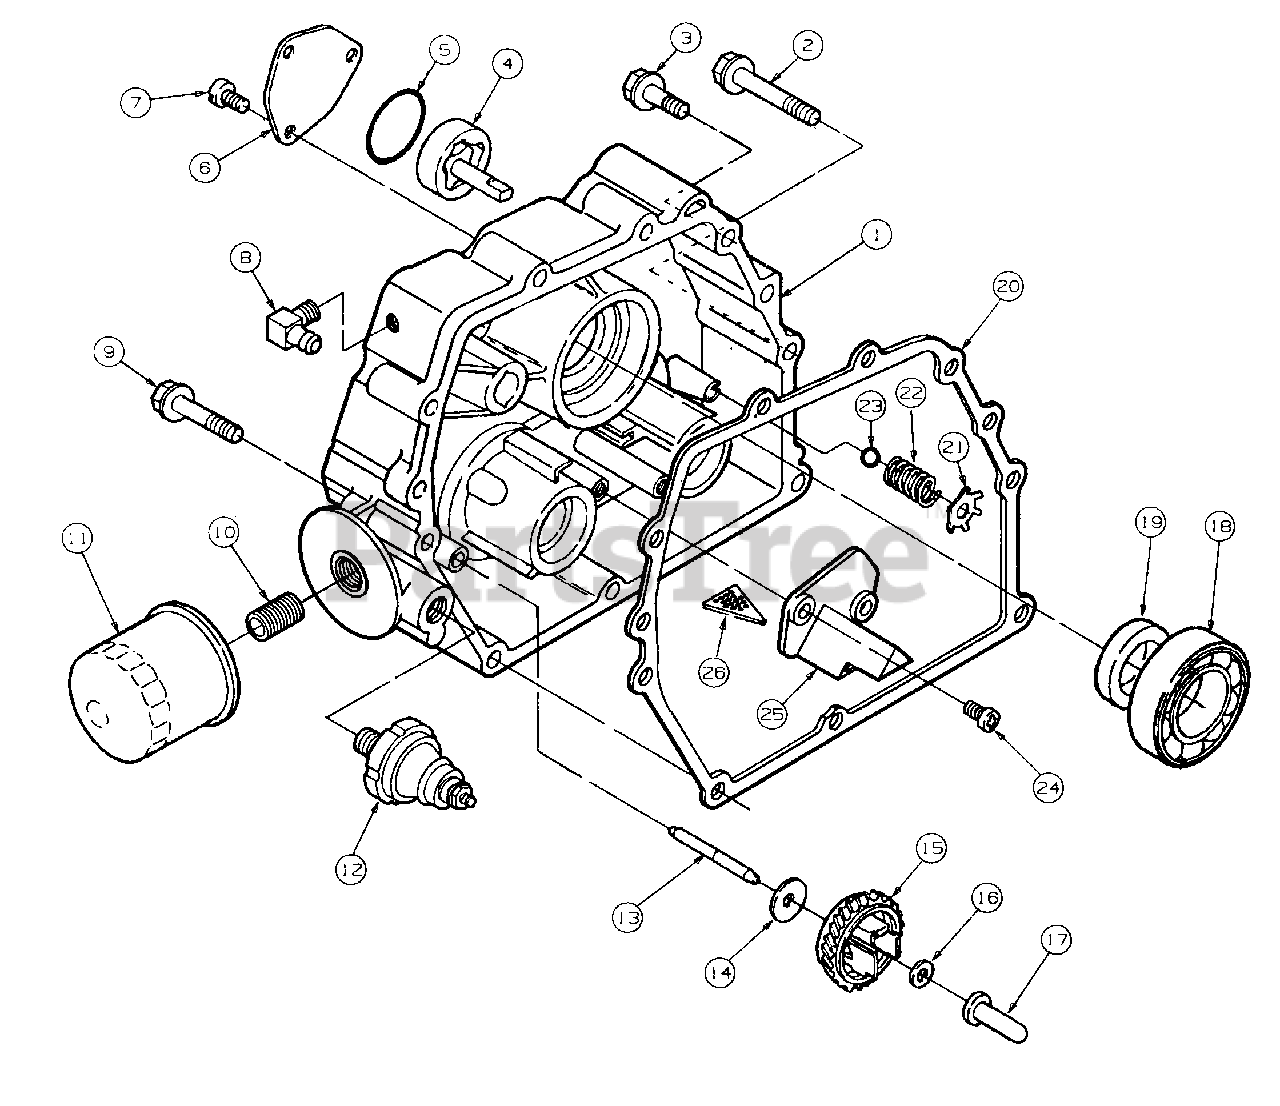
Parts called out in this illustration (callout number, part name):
2	Screw, Hex Head Flanged, Thread Forming, M8 x 1.25 x 70 mm
3	Screw, Hex Head Flanged, Thread Forming, M8 x 1.25 x 35 mm
4	Pump Assy, Oil
6	Cover, Oil Pump M6 x 1 x 14 mm
7	Screw, Pan Head Torx Drive
8	Elbow, Hose, 90°.
9	Screw, Hex Head Flanged, Thread Forming, M8 x 1.25 x 50 mm
10	Adapter, Oil Filter
12	Switch, Oil Pressure
13	Shaft, Governor
14	Washer, Flat, 6.2 mm ID x 18 mm OD x 1 mm Thk
15	Gear, Governor
16	Retainer, Governor Gear
17	Sleeve, Governor
18	Bearing, Crankshaft
19	Seal, Crankshaft Oil
20	Gasket, Gearcase
21	Ring, Retaining
22	Spring, Relief Valve
23	Ball, Steel, 5/16 OD
24	Screw, Torx Drive Pan Head, M6 x 1 x 14 mm
25	Tube, Oil Pickup
26	Screen, Oil Pickup
